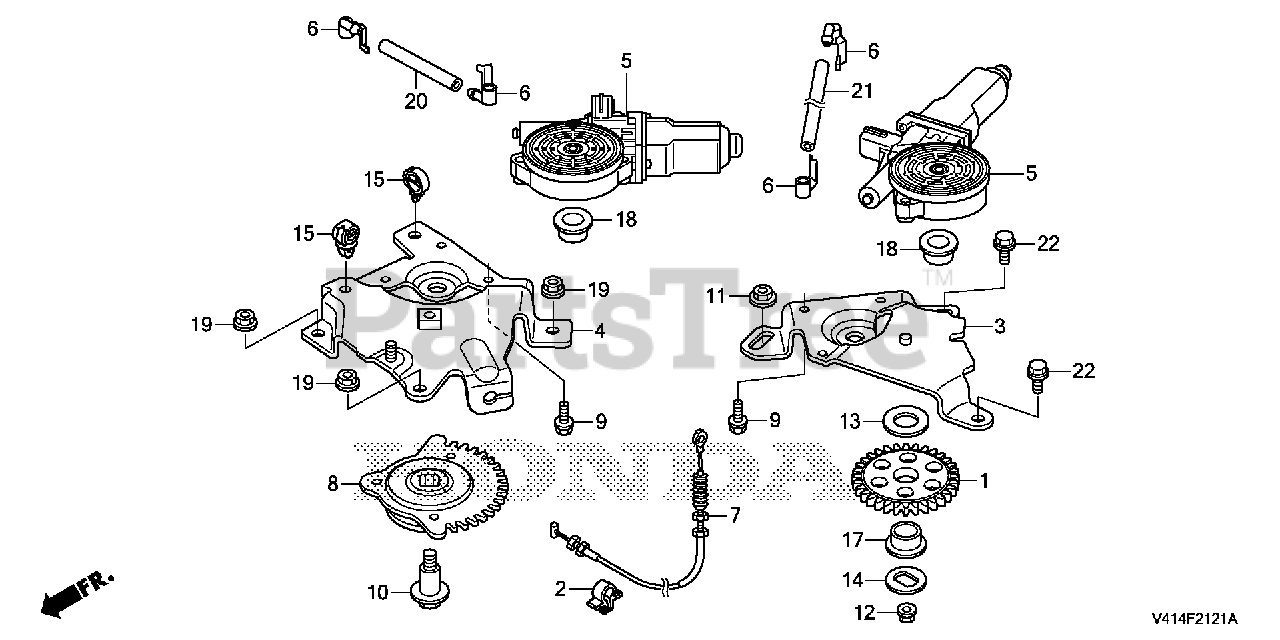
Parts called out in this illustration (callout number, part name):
1	GEAR, IDLE (32T)
2	CLIP, IGNITION WIRE
3	BRACKET, CHUTE MOTOR
4	BRACKET A, CHUTE MOTOR
5	MOTOR ASSY., CHUTE
6	CAP, WATER PROTECTION
7	CABLE, CHUTE GUIDE
8	GEAR, CHUTE GUIDE MOTOR (46T)
9	SCREW, TAPPING (5X14)
10	BOLT, SHOULDER (M8)
11	NUT, FLANGE (6MM)
12	NUT, SELF-LOCK (6MM)
13	WASHER (12.5X28X1)
14	WASHER, SPECIAL
15	CLIP, WIRE HARNESS (25MM)
16	CLIP, HARNESS BAND (145MM) (BLACK)
17	BUSH (12X6)
18	BUSH (10X5)
19	NUT, FLANGE (6MM)
20	BULK HOSE, VACUUM (4.5X1000) (4.5X025)
21	BULK HOSE, VACUUM (4.5X1000) (4.5X120)
22	BOLT, FLANGE (6X12)
